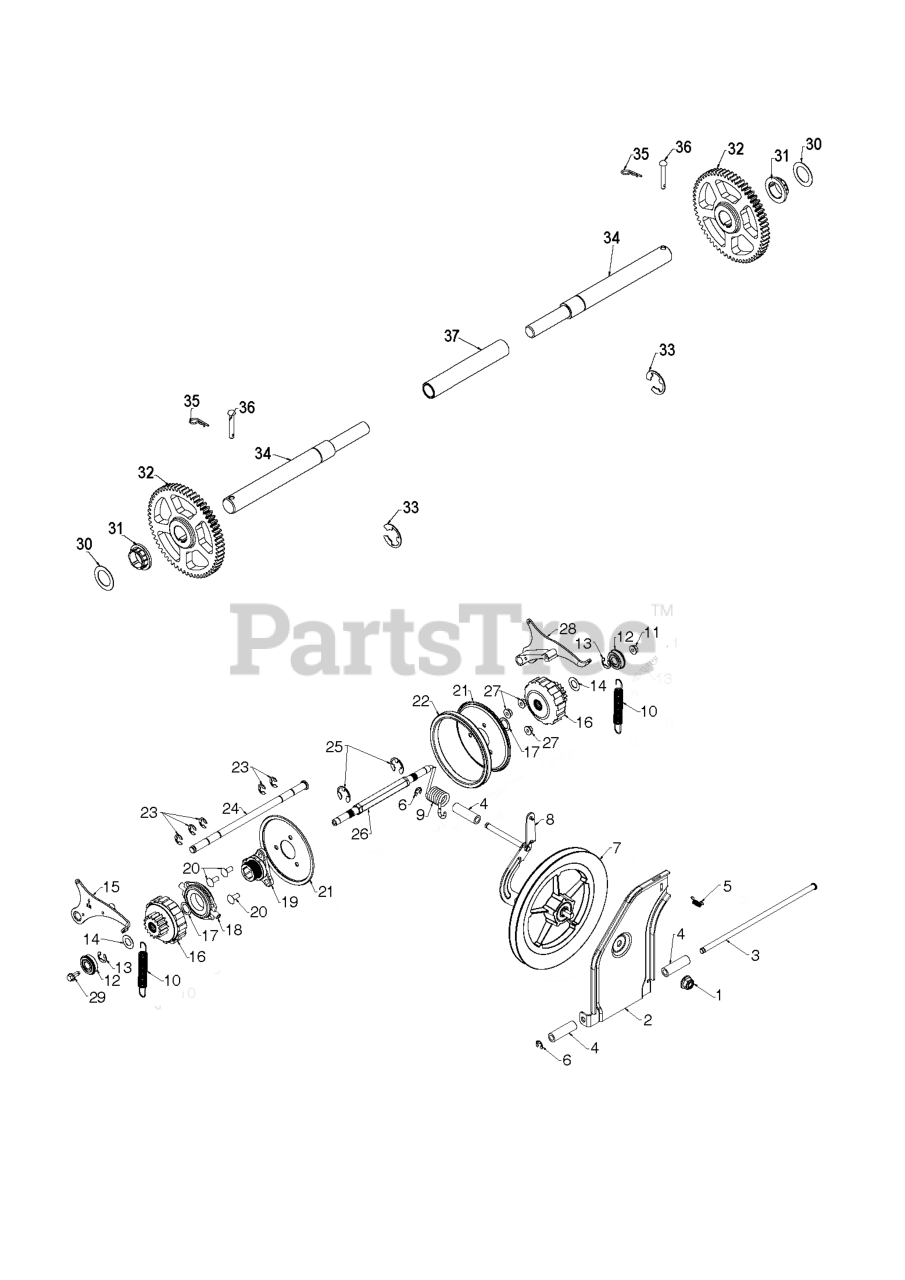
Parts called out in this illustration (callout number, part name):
1	NUT 1/2-13 HEX FLANGE NYLOK CL
2	PLATE TIP PULLEY SLOTTED MS431
3	ROD ROD,PIVOT, SWING PLATE ROD
4	SPACER YOKE, TORSION SPRING
5	SPRING LATCH
6	RETAINER RING E-RING CLEAR ZI
7	PULLEY ASSY TEXTURED TEXTURED
8	BRACKET.YOKE.ASSEMBLY.479
9	SPRING TORSION DRIVE
10	SPRING EXTENSION PS
11	NUT.HEX.FLANGE.LOCK.5/16-18
12	BEARING 9/16 ID. SNR
13	RING.RETAINING.1622-2RSNR.CLER
14	WASHER FLAT.637IDX1.00ODX21GA
15	PAWL.ASM.RH.SNOW
16	GEAR.ASM.PLANETARY
17	WASHER FLAT.59IDX1.065ODX25GA
18	BEARING HOUSING ASSY TRUNNION
19	HUB.RUBBER.WHEEL
20	BOLT.CARR.SQNK.5/16-18UNC.X3/4
21	PLATE.RUBBER.WHEEL.BLACK
22	Friction Drive
23	CLIP E-RING_.500 SHAFT
24	ROD ROD, PAWL ROD
26	Shafts
26	SHAFT SHAFT, PWR STR SHAFT
27	NUT.LOCK.5/16-18
28	PAWL.ASM.LH.SNOW
29	SCREW HEXAGON HEAD FLANGE 5/16
30	WASHER 1.00
31	BUSHING.HEX.1.SHAFT
33	E RING HYT
34	AXLE AXLE, SPLIT SHAFT
35	RETAINER M
36	RIVET
37	SLEEVE SLEEVE, AXLE SLEEVE
